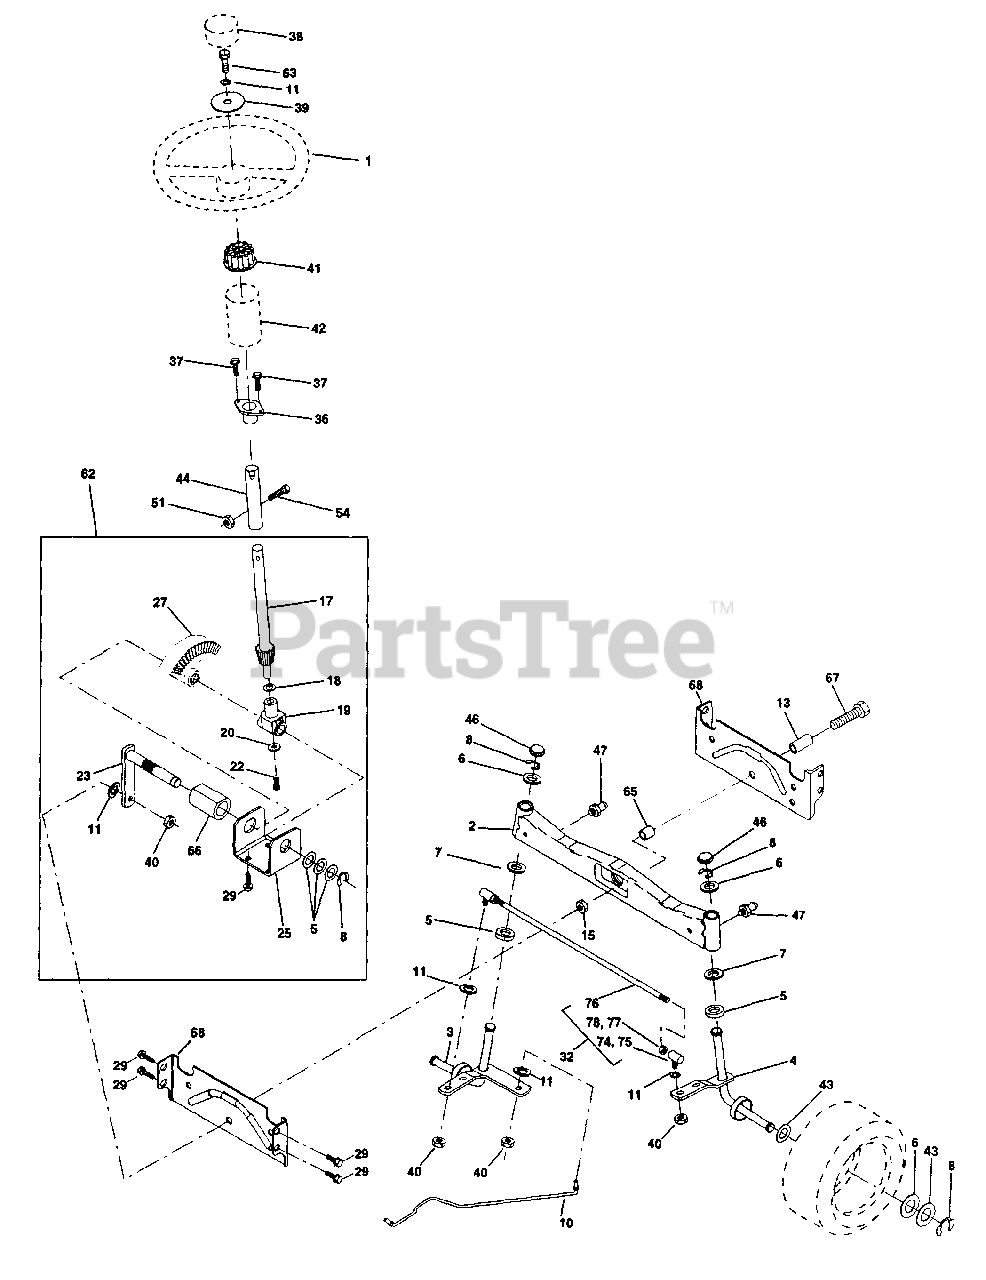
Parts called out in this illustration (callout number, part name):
1	Wheel Steering
2	Axle Front Casting Machined
3	Spindle Asm LH Cast 15"
4	Spindle Asm RH Cast 15"
5	Bearing Race Thrust Harden
6	Washer 25/32 X 1-5/8 X 16 Ga
7	Washer 27/32 X 1-1/4 X 16 Ga
8	Ring Klip #t5304-75
10	Link Drag Extended Cast
11	Washer Lock Hvy Hlcl Spr 3/8
13	Bearing Axle STLT/GT
15	Nut Lock Flange 5/8-11 Unc
17	Shaft Asm Strg
18	Washer Thrust 515 x 750 x 033
19	Support Shaft
20	Washer Shim 1/4 X 5/8 X 062
22	Screw Hex Socket 1/4-20 x 5/8
23	Shaft Asm Pittman
25	Bracket Steering
27	Gear Sector
29	Screw Thdrol 3/8-16 x 3/4 Ty-tt
32	Rod Asm Tie Ball J Adj VGT
36	Bushing Strg
38	Insert Cap Strg Wh Au
39	Washer 13/32 X 2-3/8 X 8 Ga
40	Lock nut
41	Adaptor Wheel Strg
42	Boot Steering Shaft
43	Washer 25/32 X 1 1/4 X 16 Ga
44	Extension Steering Shaft LR/LT
46	Cap Spindle Fr Top Blk
47	Fitting Grease
51	Nut Lock Hex w/Ins 5/16-18
54	Bolt Fin Hex 5/16-18 Unc x 1-1/4
62	Kit, Steering Assembly Svc
63	Bolt Fin Hex 3/8-16unc x 1 Gr. 5
65	Spacer Axle
66	Bearing Arm Pittman
67	Bolt, Fin Hex 5/8-11 UNC x 2-3/4
68	Axle, Brace
74	Joint Asm Ball Rh
75	Joint Asm Ball Lh
76	Rod Tie Ball J Adj
77	Nut Hex Jam 3/8-24 Unf Lh
78	Nut Hex Jam 3/8-24 Unf
